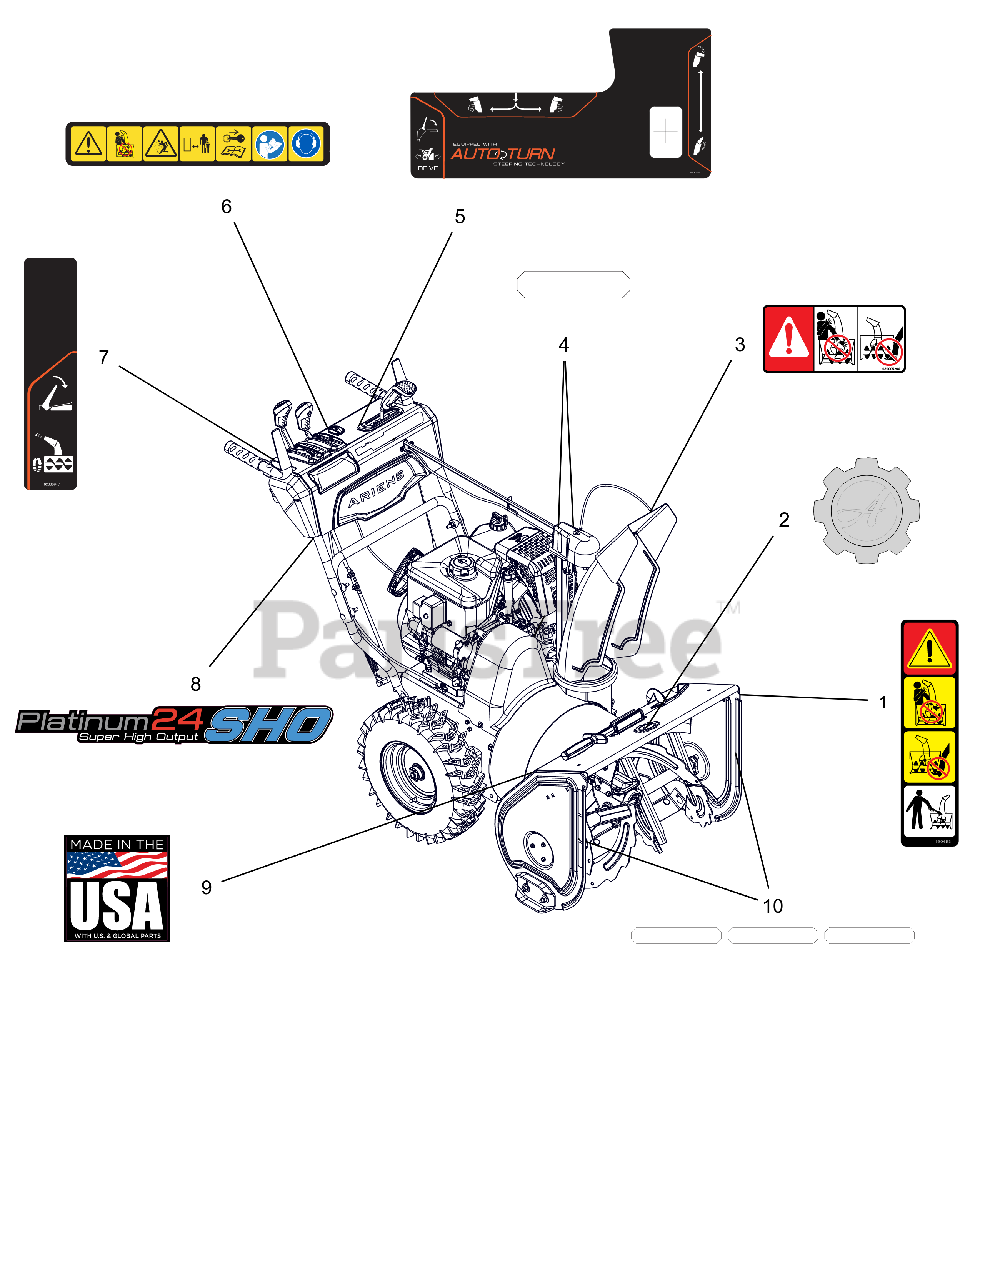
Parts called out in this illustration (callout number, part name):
1	DECAL, DANGER - ROTATING PARTS
2	DECAL, ARIENS-GEAR BADGE -THK
3	DECAL, DANGER
4	DECAL,REFLECTIVE,GEAR COVER
5	DECAL,CONTROL-LG QT2
6	DECAL,DASH - SAFETY
7	DECAL,CONTROL-RH CONTROL
8	DECAL, DASH, PLATINUM 24 SHO
9	DECAL, MADE IN USA
10	DECAL,REFLECTIVE,HOUSING
